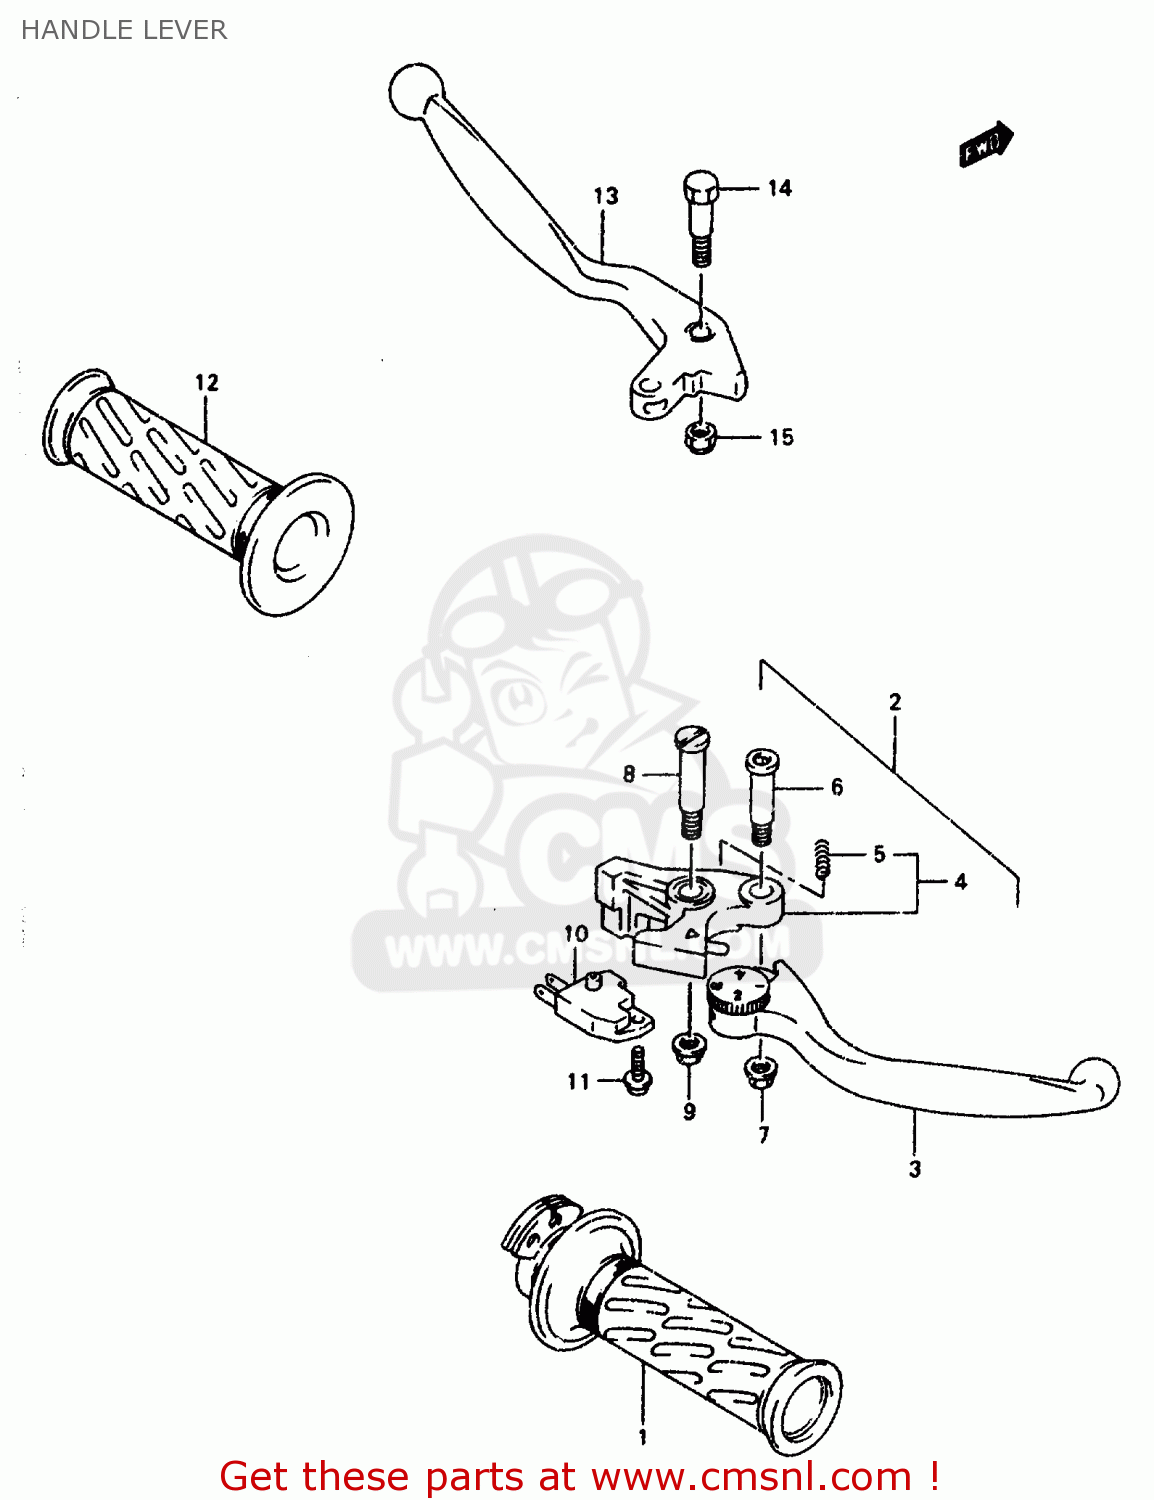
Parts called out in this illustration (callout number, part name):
1	GRIP,THROTTLE
2	LEVER ASSY,BRAKE
3	LEVER,ADJUST
4	KNOCKER
5	SPRING
6	BOLT,LEVER
7	NUT
8	BOLT,LEVER PIVOT
9	NUT
10	SWITCH ASSEMBLY,STOP
11	SCREW
12	GRIP,LEFT
13	LEVER,CLUTCH (SILVER)
14	BOLT,LEVER
18	NUT
